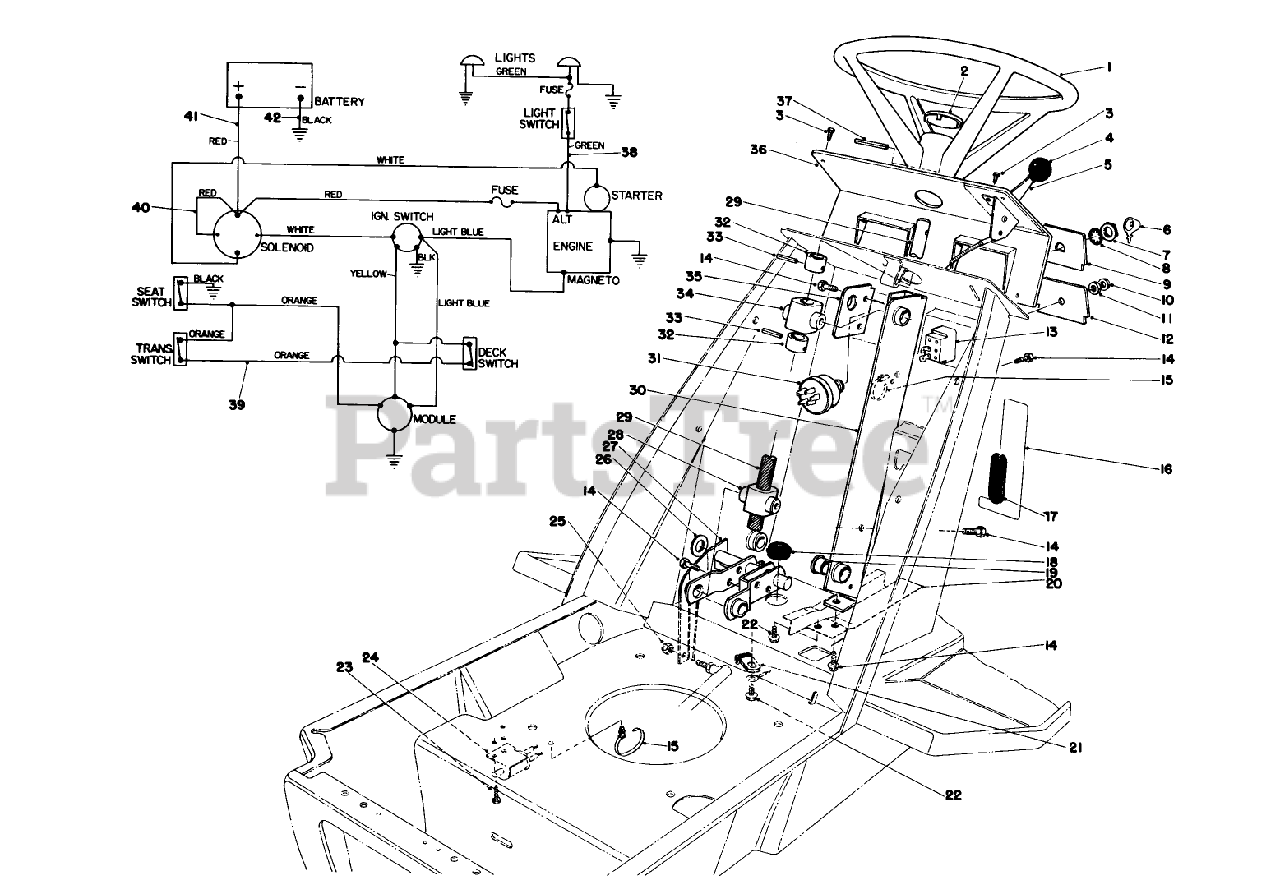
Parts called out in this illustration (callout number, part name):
3	SCREW-HWHTF
4	KNOB-CONTROL
5	THROTTLE CONTROL
7	NUT-HH
8	WASHER-LOCK
11	NUT-LOCK
13	SWITCH-LIGHT
14	SCREW-THD ROLL, HWH
15	TIE-MOUNT, PUSH
18	GROMMET
19	BEARING-FLANGE
21	CLIP-FUEL LINE
22	SCREW-HWH
23	SCREW-TAPTITE
29	STEERING SHAFT
31	SWITCH-STARTER
32	STRG SHAFT COLLAR
33	PIN-SPRING
37	PIN-ROLL
41	WIRE ASM
42	WIRE ASM
